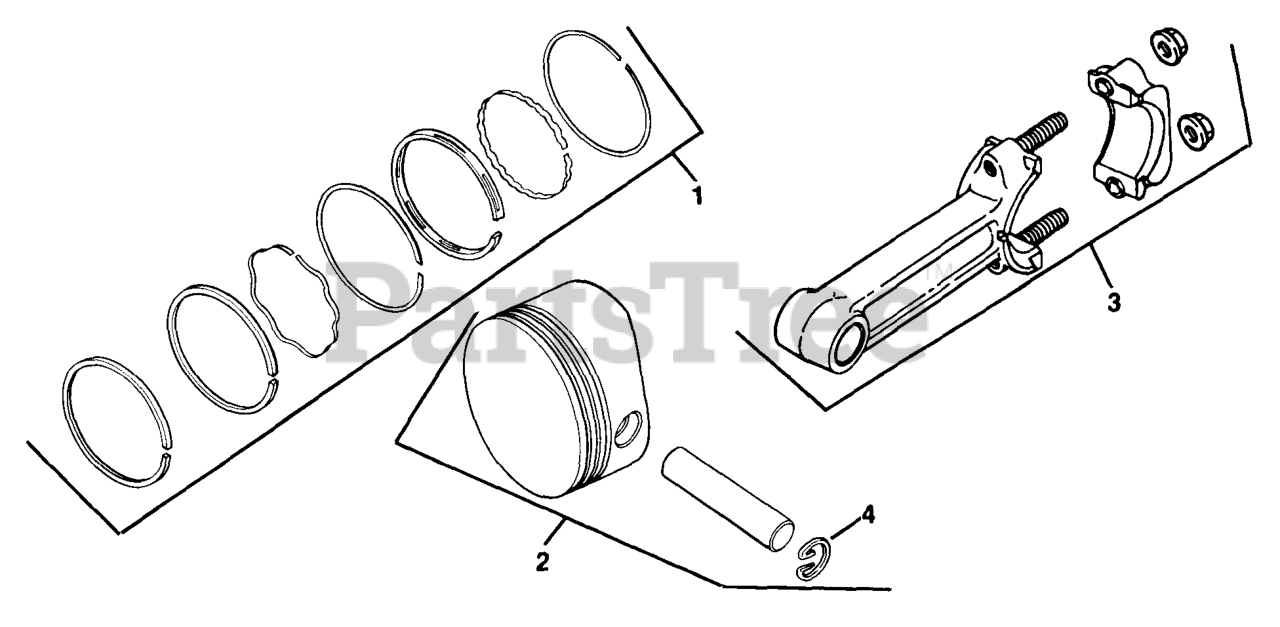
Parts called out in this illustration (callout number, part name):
1	RINGS - USE 52 108 09
1	RINGS - USE 52 108 10
1	RINGS - USE 52 108 11
1	RING - USE 52 108 12
2	PISTON SET - USE 52 874 01
2	PISTON SET - USE 52 874 02
2	PISTON SET - USE 52 874 03
2	PISTON SET - USE 52 874 04
2	PISTON SET - USE 52 874 05
3	ROD - USE 52 067 67
3	ROD - USE 52 067 68
4	RING, RETAINING
